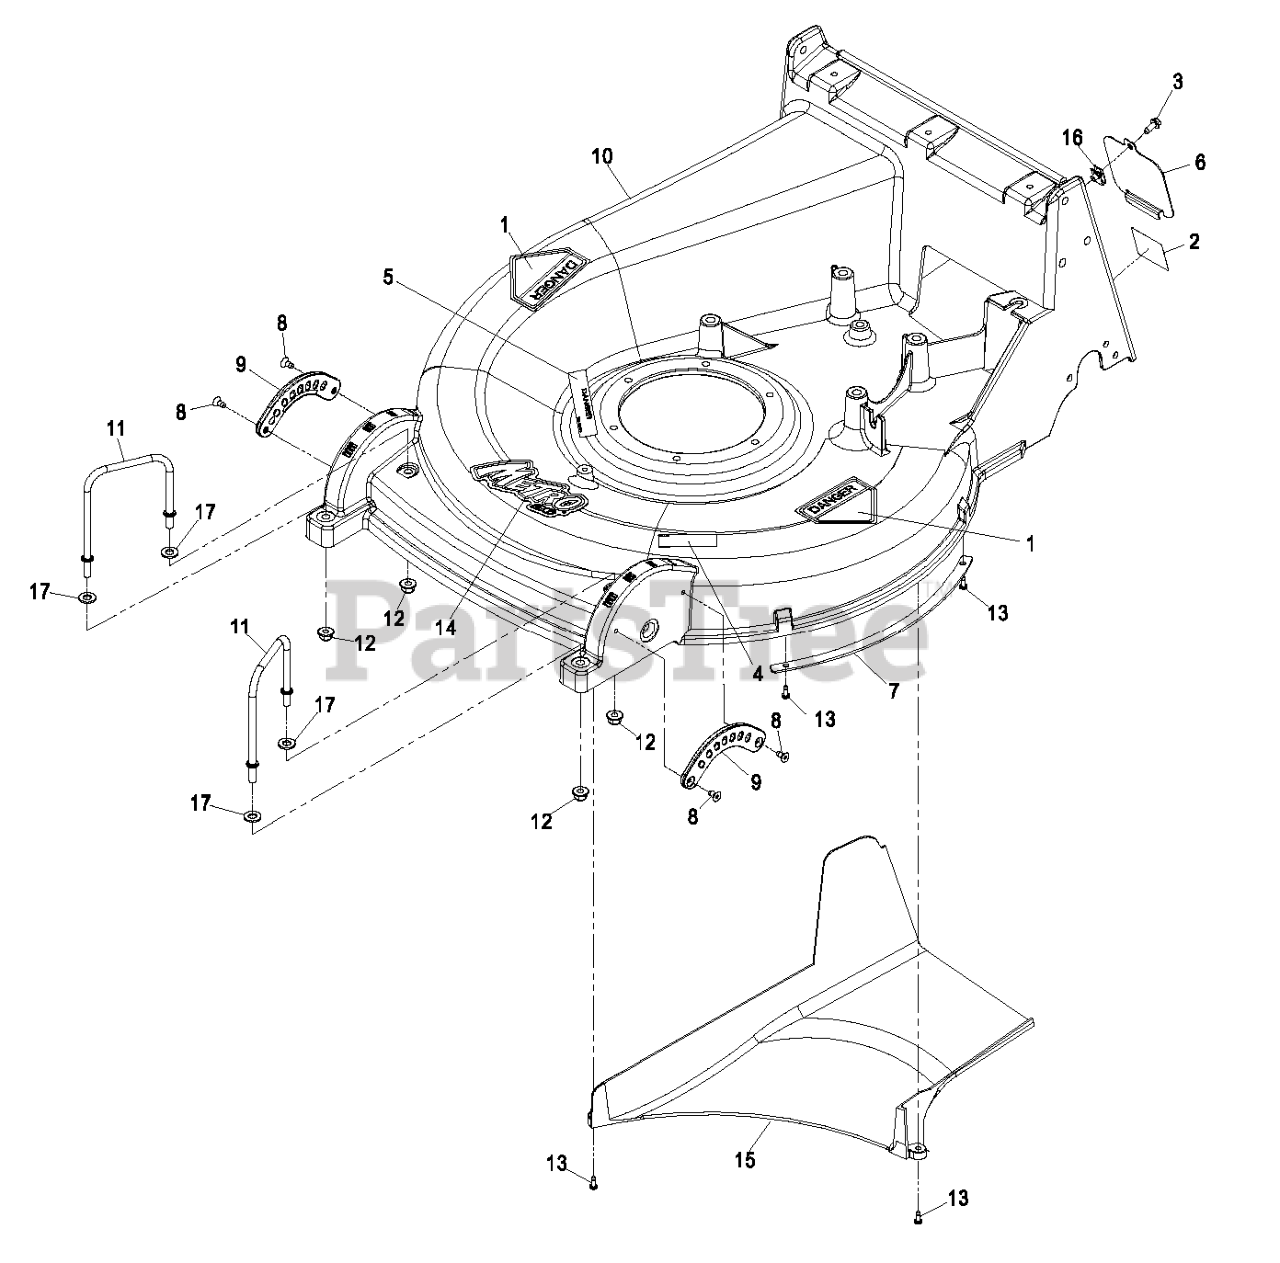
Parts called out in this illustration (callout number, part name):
1	DECAL-DANGER
2	DECAL,SERVICE M26
3	SCREW-HWH
4	DECAL-BLADE
5	DECAL-COVER, MISSING
7	PLATE-SKID
9	QUADRANT-FRONT
10	ASM,DECK M26 W/DECALS
12	NUT-HF, NI
14	DECAL,METRO 26
16	Nut, Retainer-Panel 1/4-20
17	WASHER-FLAT
